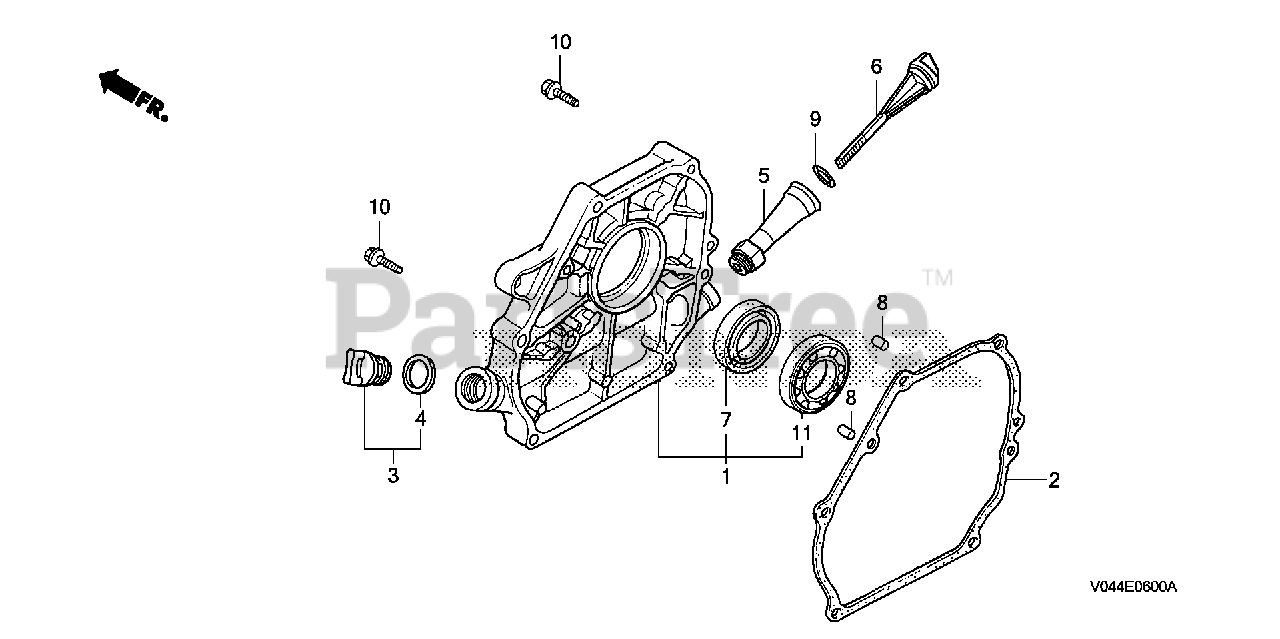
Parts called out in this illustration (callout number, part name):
1	COVER ASSY., CRANKCASE
2	GASKET, CASE COVER (NON-ASBESTOS)
2	GASKET, CASE COVER
3	CAP ASSY., OIL FILLER
4	GASKET, OIL FILLER CAP
5	PIPE, OIL FILLER
6	DIPSTICK, OIL
7	OIL SEAL (25X41X6)
8	PIN A, DOWEL (8X14)
9	O-RING (23X2.8)
10	BOLT, FLANGE (8X32)
11	BEARING, RADIAL BALL (6205)
